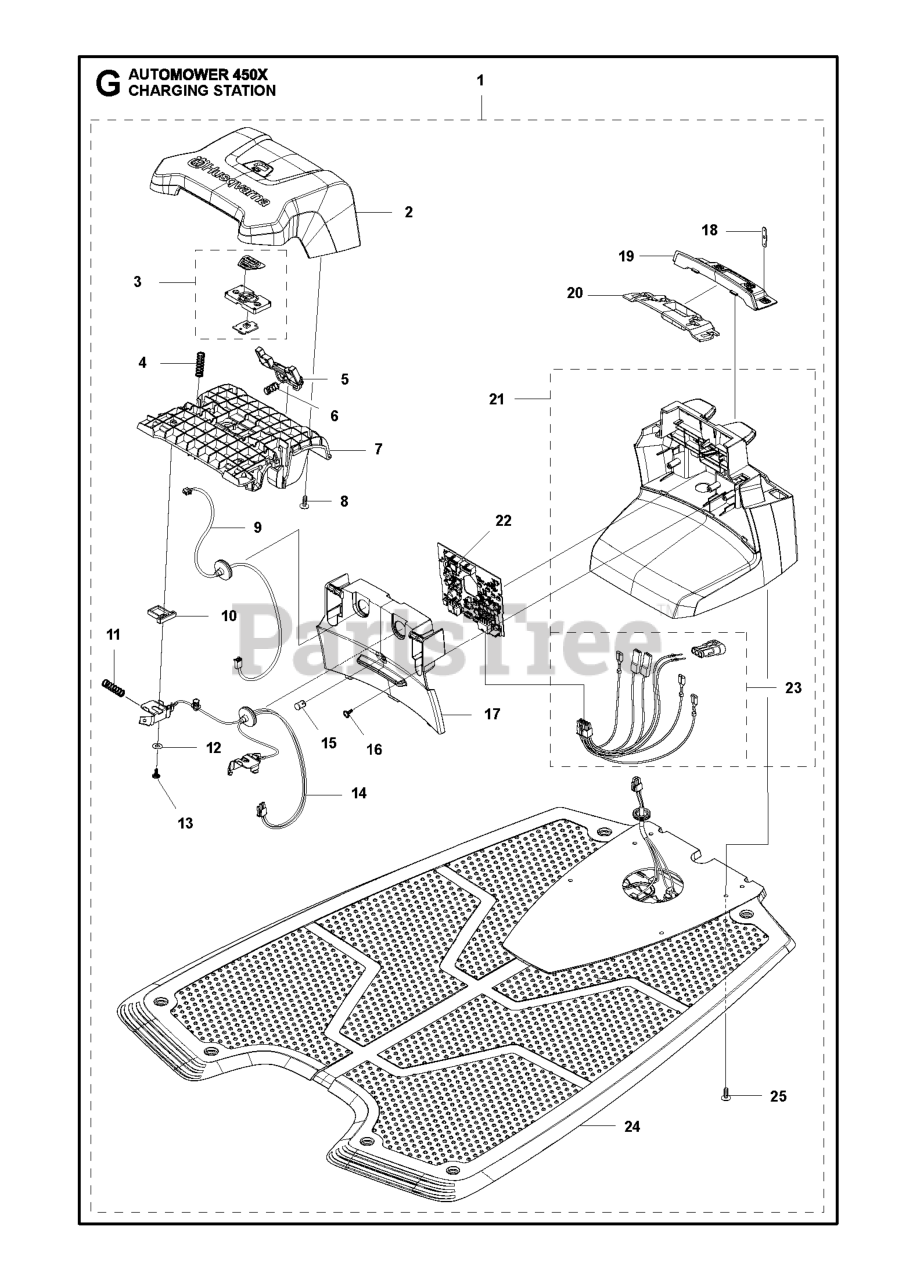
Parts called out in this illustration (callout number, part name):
1	CHARGING STATION ASSY 450X
2	CAP CHARGING STATION WITHOUT H
3	BUTTON KIT HOME
4	SPRING SPRING CAP
5	BUTTON CHARGING STATION, RELEA
6	SPRING STOP BUTTON
7	FRAME CHARGING STATION
8	SCREW 14MM
9	LOOM HOME BUTTON
10	DISTANCE CHARGING STATION
11	SPRING SPRING CAP
13	SCREW 14MM
14	LOOM CHARGING CONTACTS
15	LENS
16	SCREW 14MM
17	LID CHARGING STATION 330, TWO
18	TERMINAL TERMINAL CHARGING STA
19	PANEL CHARGING STATION 340, TH
20	HOLDER CHARGING STATION
21	HOUSING ASSY CHARGING STATION
22	PRINTED CIRCUIT ASSY PCBA CS B
23	CABLE KIT GENERATOR BOARD
24	CHARGING PLATE CHARGING PLATE
25	SCREW 14MM
